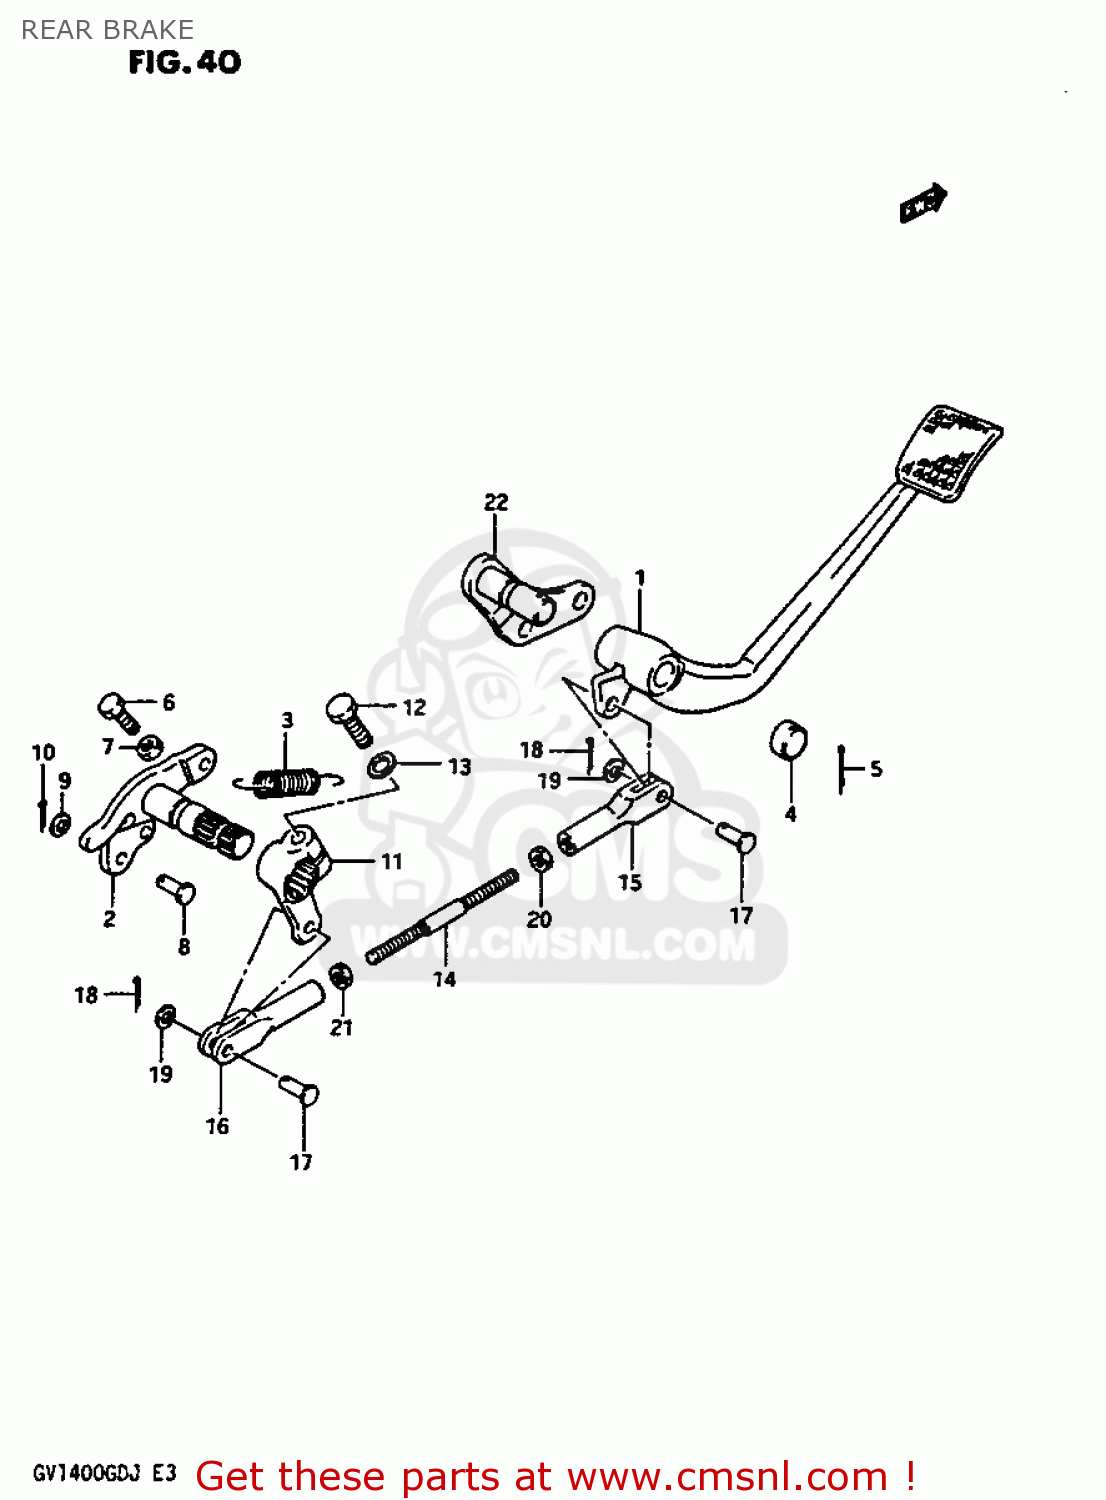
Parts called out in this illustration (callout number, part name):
1	PEDAL COMP,BRAKE
2	ARM,REAR MASTER CYLINDER
3	SPRING
4	CAP,BRAKE PEDAL
5	COTTER PIN
6	BOLT(6X23)
7	NUT
8	PIN
9	WASHER
10	PIN
11	ARM,BRAKE PEDAL LINK
12	BOLT
13	LOCK WASHER
14	LINK,BRAKE PEDAL
15	JOINT,BRAKE PEDAL,FRONT
16	JOINT,BRAKE PEDAL,REAR
17	PIN
18	PIN 20X20
19	WASHER
20	NUT
21	NUT
22	BAR,BRAKE PEDAL BOSS
